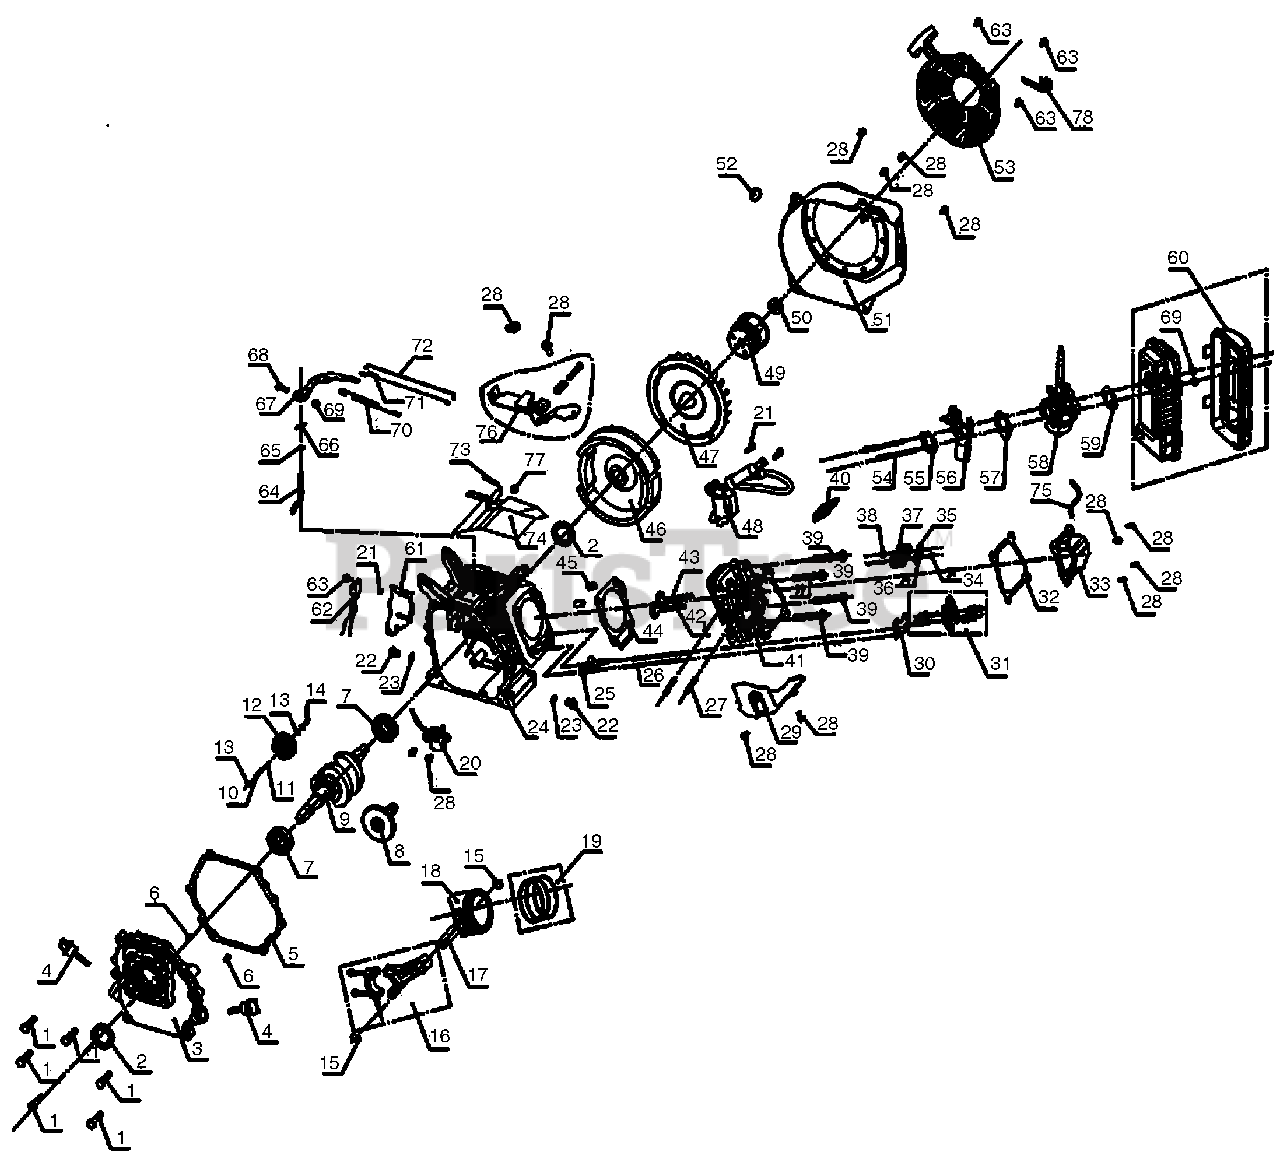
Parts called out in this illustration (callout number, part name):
0H3375B00SM	208cc GASOLINE ENG (G24) SM Kit
1	BOLT, M8X33.5
2	SEAL, OIL, CRANKSHAFT
3	COVER, CRANKCASE
4	DIPSTICK, OIL W/ ORING
5	GASKET, CRANKCASE
6	PIN,SET, M8X14
7	BEARING, (6205)
8	CAMSHAFT ASSY.
9	CRANKSHAFT ASSY.
10	SHAFT, REGULATING
11	RING, SNAP
12	GEAR, SPEED GOVERNING
13	WASHER, SPEED SWINGING ROD
14	DISH, SPEED GOVERNING PUSH
15	CIRCLIP, PISTON RING
16	ROD ASSY., CONNECTING
17	PIN, PISTON
19	RING SET, PISTON
20	SENSOR, OIL
21	BOLT, M6X22
22	PLUG, DRAIN
23	WASHER, DRAIN PLUG
24	CRANKCASE
26	ROD, PUSH
27	STUD, AM 8X34
28	BOLT, M6X12
29	COVER, LEAD WIND
30	GUIDE, PUSH
31	ROCKER, ASSEMBLY, VALVE
32	GASKET, CYLNDR HEAD CVR
33	COVER, CYLINDER HEAD
35	SEAT, INTAKE SPRING
36	SEAT, EXHAUST SPRING
37	SPRING, VALVE
38	SEAL, OIL PIPE
39	BOLT, M8 X 60
40	PLUG, SPARK
41	HEAD, CYLINDER
42	VALVE, EXHAUST
43	VALVE, INTAKE
44	GASKET, CYLINDER HEAD
47	FAN, FLYWHEEL
48	COIL ASSY., IGNITION
49	CUP, STARTING
50	NUT, M14X1.5
51	HOOD, FAN
52	JAM, RUBBER
53	STARTER ASSY., RECOIL
54	STUD, M6 X 105
55	GASKET, INTAKE
56	BLOCK, CONNECTING
57	GASKET, CARBURETOR
58	CARBURETOR ASSY 3250 UP PH3
59	GASKET, AIR CLEANER
60	CLEANER, AIR
61	SHROUD, COMPLETE
62	VALVE, SHEET WIZARD
63	BOLT, M6 X 8, SMALL HEAD
64	BAR, SWAY, REGULATING
66	PIN, SPLIT
67	ARM, REGULATING
68	BOLT, LOCK
70	SPRING, BACK
71	SPRING, REGULATING
72	ROD, PULLING
73	BOLT, M5 X 30
74	HOOD, UPPER WIND
75	TUBE, BREATHING
76	REGULATOR ASSY.
78	EVAPORATION PIPE CLAMP
